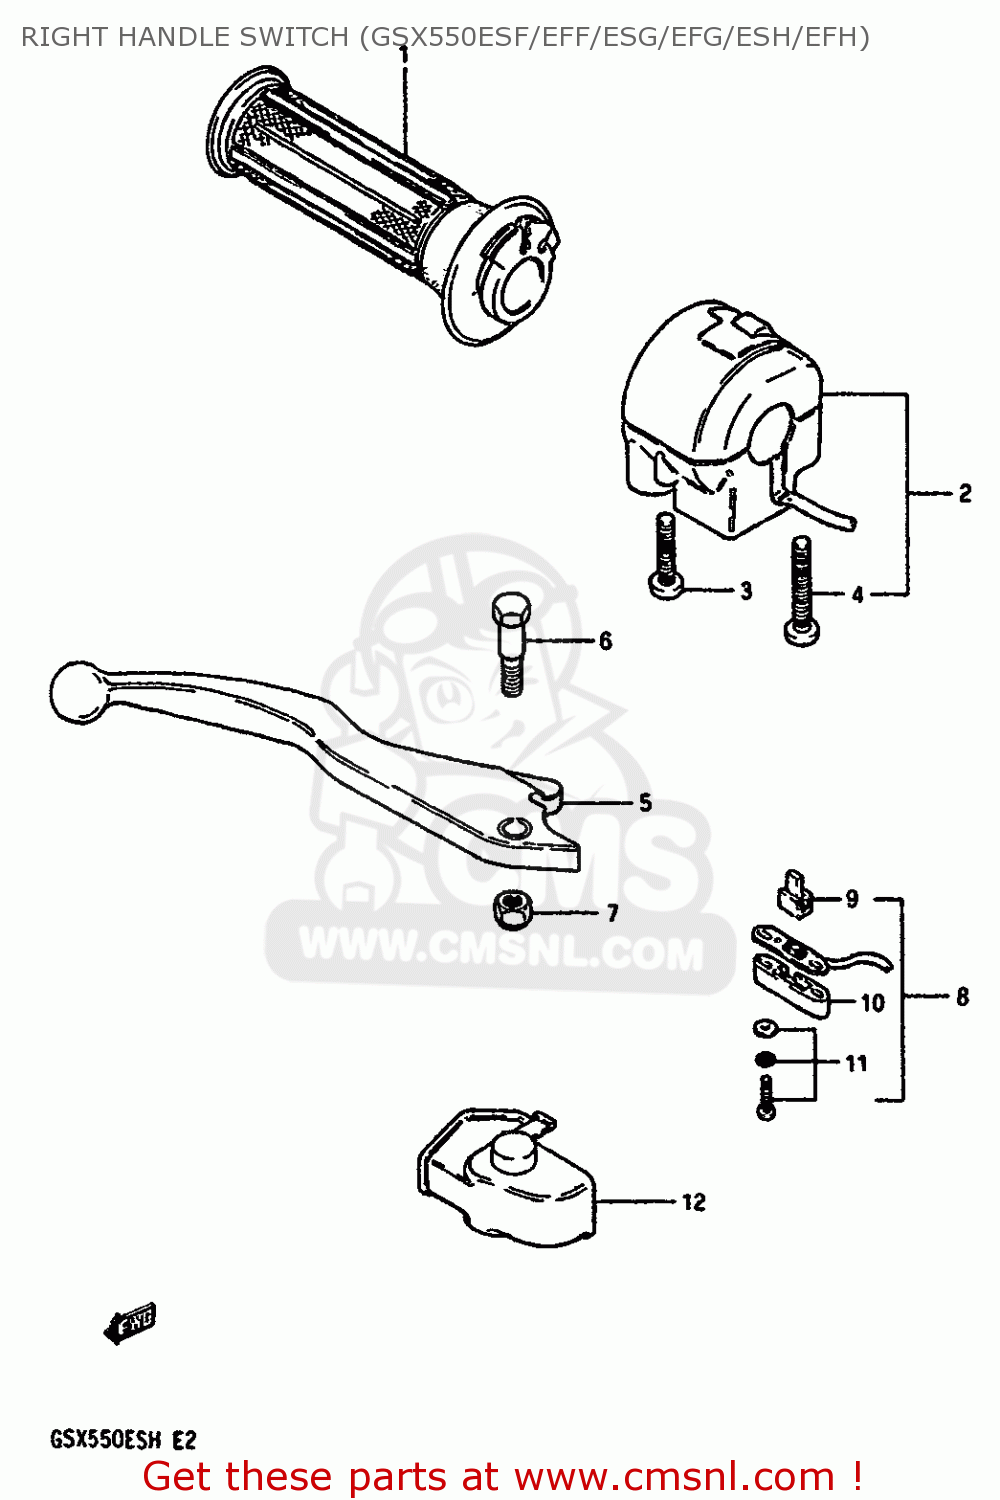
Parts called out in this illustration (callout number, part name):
1	GRIP,THROTTLE
2	SWITCH ASSY, HANDLE
3	SCREW
4	SCREW
5	LEVER,BRAKE
6	BOLT,LEVER PIVOT
7	NUT
8	SWITCH ASSEMBLY
9	CONTACT,SWITCH
10	COVER,FR BK TERMINAL BASE
11	SCREW
12	COVER,BRAKE LEVER
